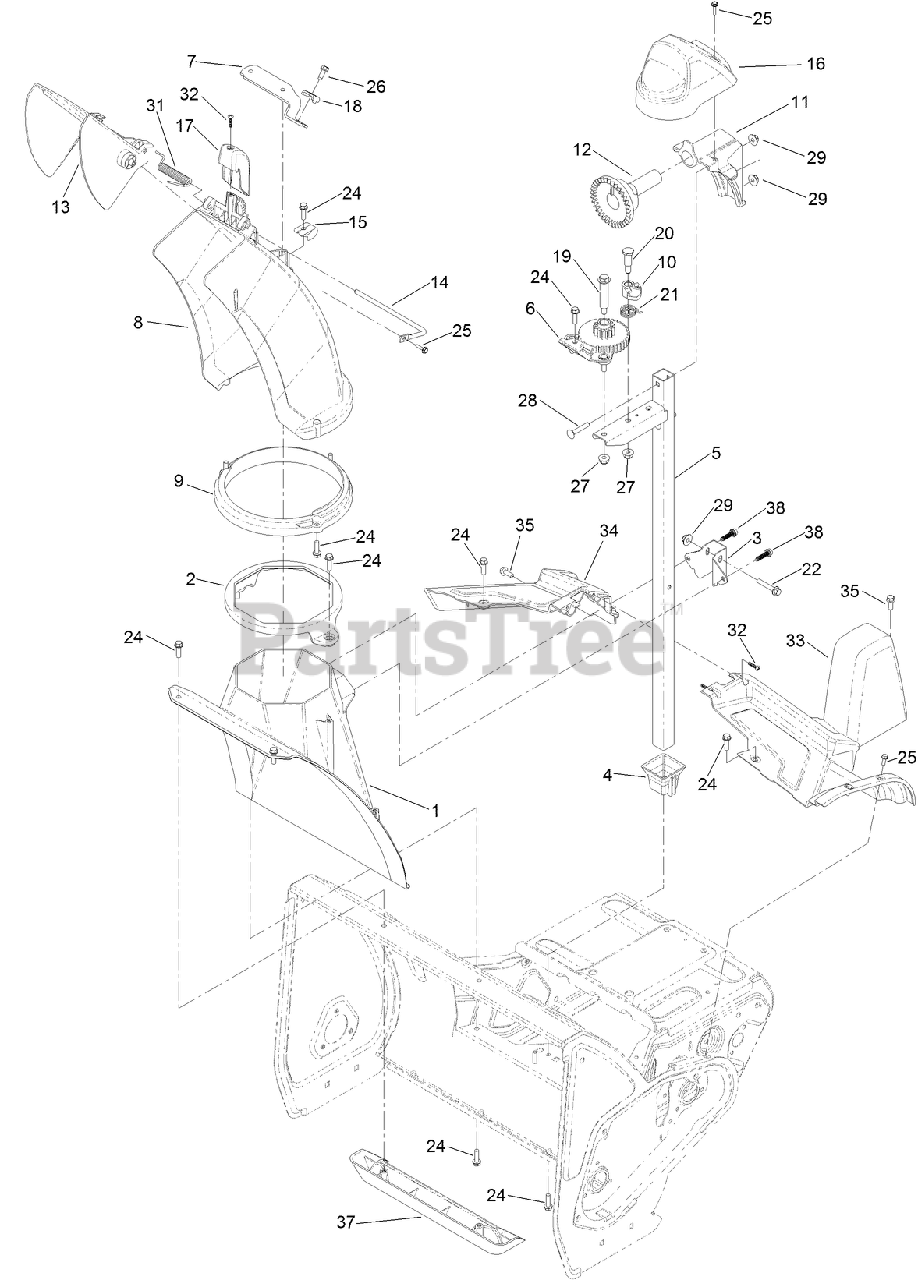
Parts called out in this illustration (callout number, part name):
1	CHUTE-LOWER
2	GUIDE-CHUTE
3	BRACKET-POST, SUPPORT (CHUTE)
4	RETAINER- POST, CHUTE
5	POST-CHUTE
6	GEAR-CHUTE
7	BRACKET-CABLE
9	RING-CHUTE
10	LATCH-CHUTE
11	MOUNT-GEAR, CHUTE
12	GEAR-FACE
13	DEFLECTOR-CHUTE
14	ROD-DEFLECTOR
15	GUIDE-CABLE
16	COVER-GEAR, CHUTE
17	CHUTE-COVER
18	CLAMP-CABLE
19	BOLT-SHOULDER
20	SCREW-SHOULDER
21	SPRING-TORSION, LATCH (CHUTE)
22	SCREW-HHF
24	SCREW-HWH
25	SCREW-HWH
26	SCREW-HWH
27	NUT-HF, NI
28	SCREW-CARR
29	NUT-HF
31	SPRING-TORSION
32	SCREW-PPH
33	SHROUD-UPPER, LH
34	SHROUD-LOWER, RH
35	SCREW-HWH
37	KICKER-HOUSING
38	SCREW-FLANGE, PLASTIC
